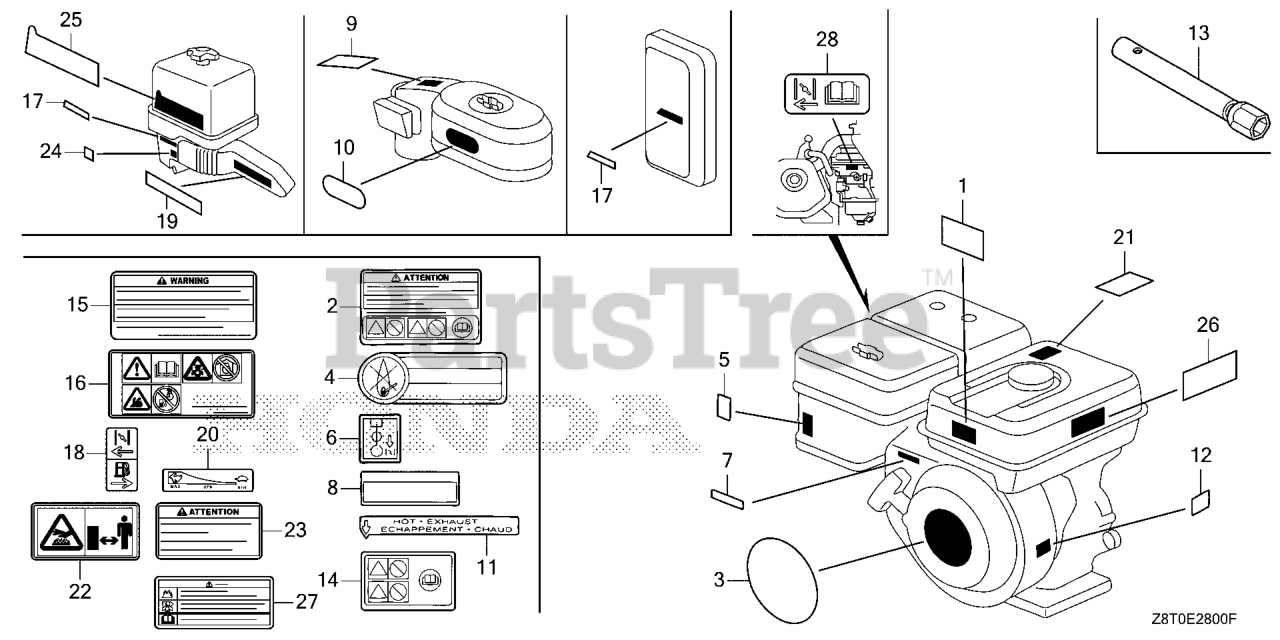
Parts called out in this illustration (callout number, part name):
3	EMBLEM (GX340)
4	MARK, CAUTION (ENGLISH/FRENCH)(SPANISH)
6	MARK, CHOKE
8	MARK, AIR CLEANER (ENGLISH)
11	MARK, EX. CAUTION (ENGLISH/FRENCH)
12	MARK, OIL CAUTION
